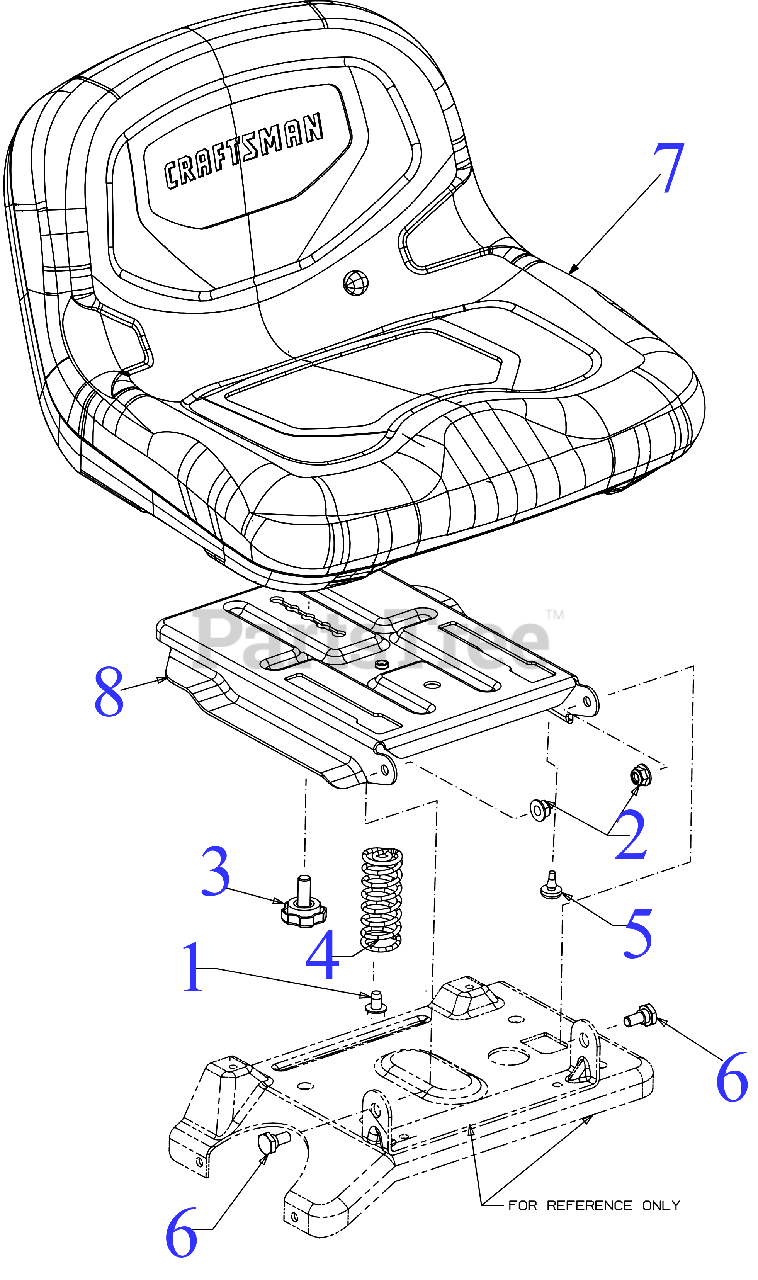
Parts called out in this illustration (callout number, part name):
1	SCREW 5/16-18 x .500
2	FLANGE LOCK NUT 5/16-18
3	SEAT ADJUSTMENT KNOB
4	SEAT SPRING
5	RUBBER BUMPER
6	SHOULDER SCREW .437 DIA x .180
7	MED BACK SEAT, BLACK (3PT)
8	MANUAL SEAT ADJUSTMENT BRACKET
